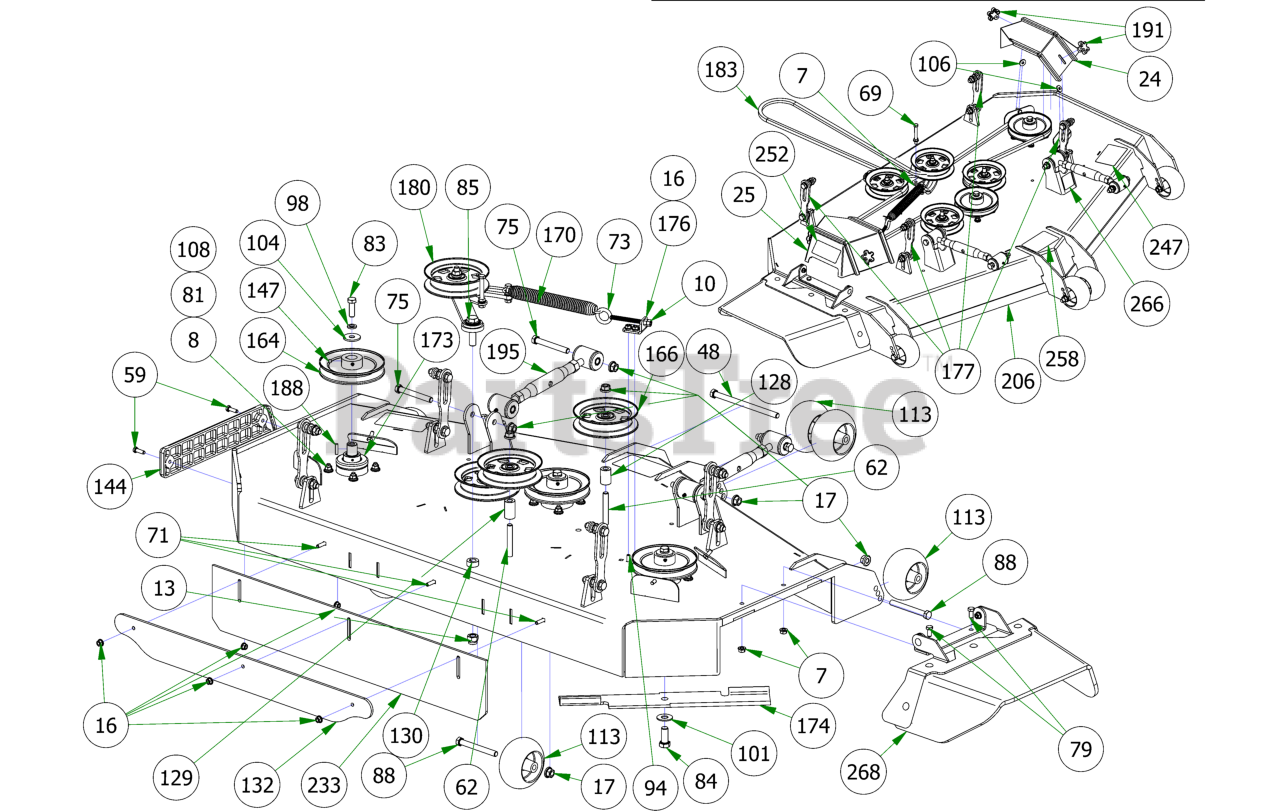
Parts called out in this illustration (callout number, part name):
7	3/8-16 HEX SERRATED FLANGE NUT HARD/ZINC
8	3/8-16 NYLON INSERT FLANGE LOCKNUT (GR.F) ZINC
10	3/8-16 HEX NUT ZINC
13	5/8-11 NYLON INSERT LOCKNUT ZINC
16	5/16-18 NYLON INSERT FLANGE LOCKNUT ZINC
17	1/2-13 NYLON INSERT FLANGE LOCKNUT ZINC
24	2019 61" Outlaw Gen2 Pulley Cover Left
25	2019 61" Outlaw Gen2 Pulley Cover Right
48	1/2-13 X 8 HEX CAP SCREW GR 5 ZINC
59	5/16-18 X 1 HEX CAP SCREW (GR.5) ZINC
62	1/2-13 X 3-1/2 HEX FLANGE BOLT (GR.8) ZINC
69	3/8-16 X 3 HEX CAP SCREW (GR.5) ZINC
71	5/16-18 X 1-1/4 CARRIAGE BOLT ZINC
73	4" 3/8-16 Eye Bolt
75	1/2-13 X 4 HEX CAP SCREW (GR.8) ZINC YELLOW
79	3/8-16 X 3/4 HEX CAP SCREW (GR.5) ZINC
81	3/8-16 X 1-1/2 HEX CAP SCREW (GR.5) ZINC
83	1/2-20 X 1-1/2 HEX CAP SCREW (GR.5) ZINC
84	5/8-18 X 1-1/2 HEX CAP SCREW (GR.8) ZINC YELLOW
85	5/8-11 X 2-1/2 HEX CAP SCREW (GR.5) ZINC
88	1/2-13 X 4-1/2 HEX CAP SCREW (GR.5) ZINC
94	5/16-18 X 7/8 CARRIAGE BOLT ZINC
98	1/2 SPLIT LOCKWASHER (GR.8) ZINC/YELLOW
101	5/8 USS FLAT WASHER (1-3/4" OD) GR.8 ZINC YELLOW
104	1/2 BELLEVILLE WASHER (1-5/8 OD X .140 THK) ZINC
106	.360 ID X .983 OD X .120 THICK FLAT WASHER NYLON BLACK
108	5/16 USS FLAT WASHER (7/8 OD) ZINC
113	2019 Deck Wheel
128	.502 ID X .750 OD X 1.500 Long Spacer
129	1 3/4" Pulley Spacer
130	5/8 SOLID SHAFT COLLAR (W/1 SET SCREW) ZINC
132	61 Bolt in Baffle Deck v2 Stripping Plate
144	REVISED TRIM BUMPER_20180226
147	5/16-24 X 1/4 SOCKET SET SCREW (CUP PT) PLAIN
164	6 1/4" Drive Pulley
166	5-3/4 Idler Pulley
170	2019 Outlaw Gen2 Deck Spring
173	OUTLAW SPINDLE ASSEMBLY
174	61 inch Fusion Blade
176	2019 Deck Eye Bolt Tab
177	Deck Hangar Assembly
180	2019 Renegade Deck Idler
183	Deck Belt for 61" Renegade
188	1/4 X 1 SQ MACHINERY KEY 1018 STL PLN
191	5/16" Knob
195	Turnbuckle
206	2019 Sloped 61" Deck
233	R Series Rubber For Deck
247	2018 61" Deck Decal
252	Danger Decal-Spindle/Discharge
258	2019 Renegade Deck Belt Route Decal
266	Deck Impact Patent Decal 9591803
268	2019 Outlaw Gen2 Chute Assembly
